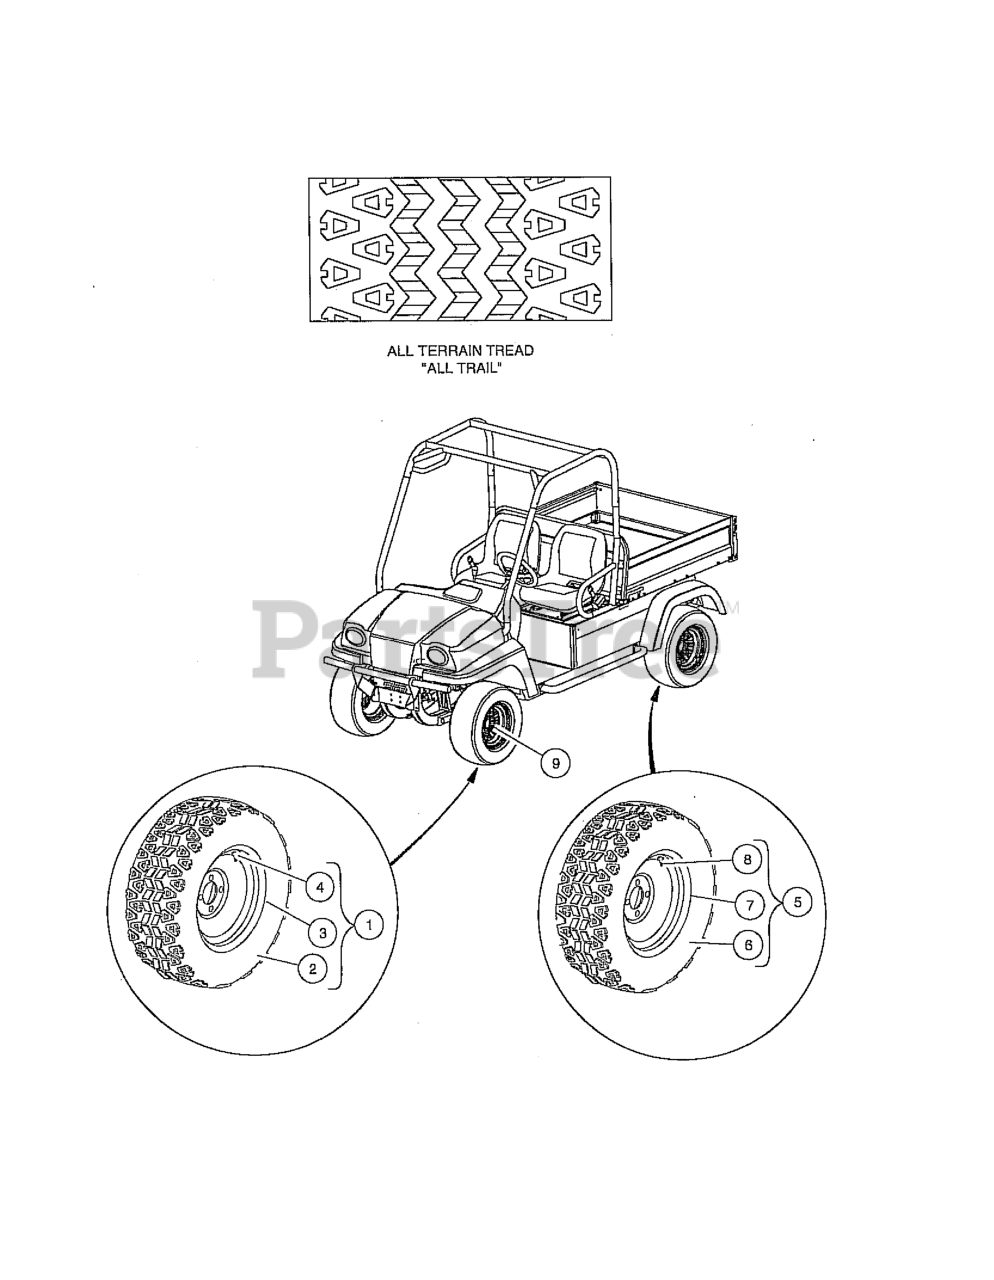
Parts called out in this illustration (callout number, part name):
1	Gray Tire Assembly, HDAT, 8-Inch
2	HDAT Tire, 8"
3	Wheel, Indus Spider, Gray
5	Gray Tire Assembly, HDAT 10.5-Inch
6	Tire, HDAT
7	Wheel, Indus Spider, Gray
9	NUT, LUG 1/2-20, SAE J 2283
